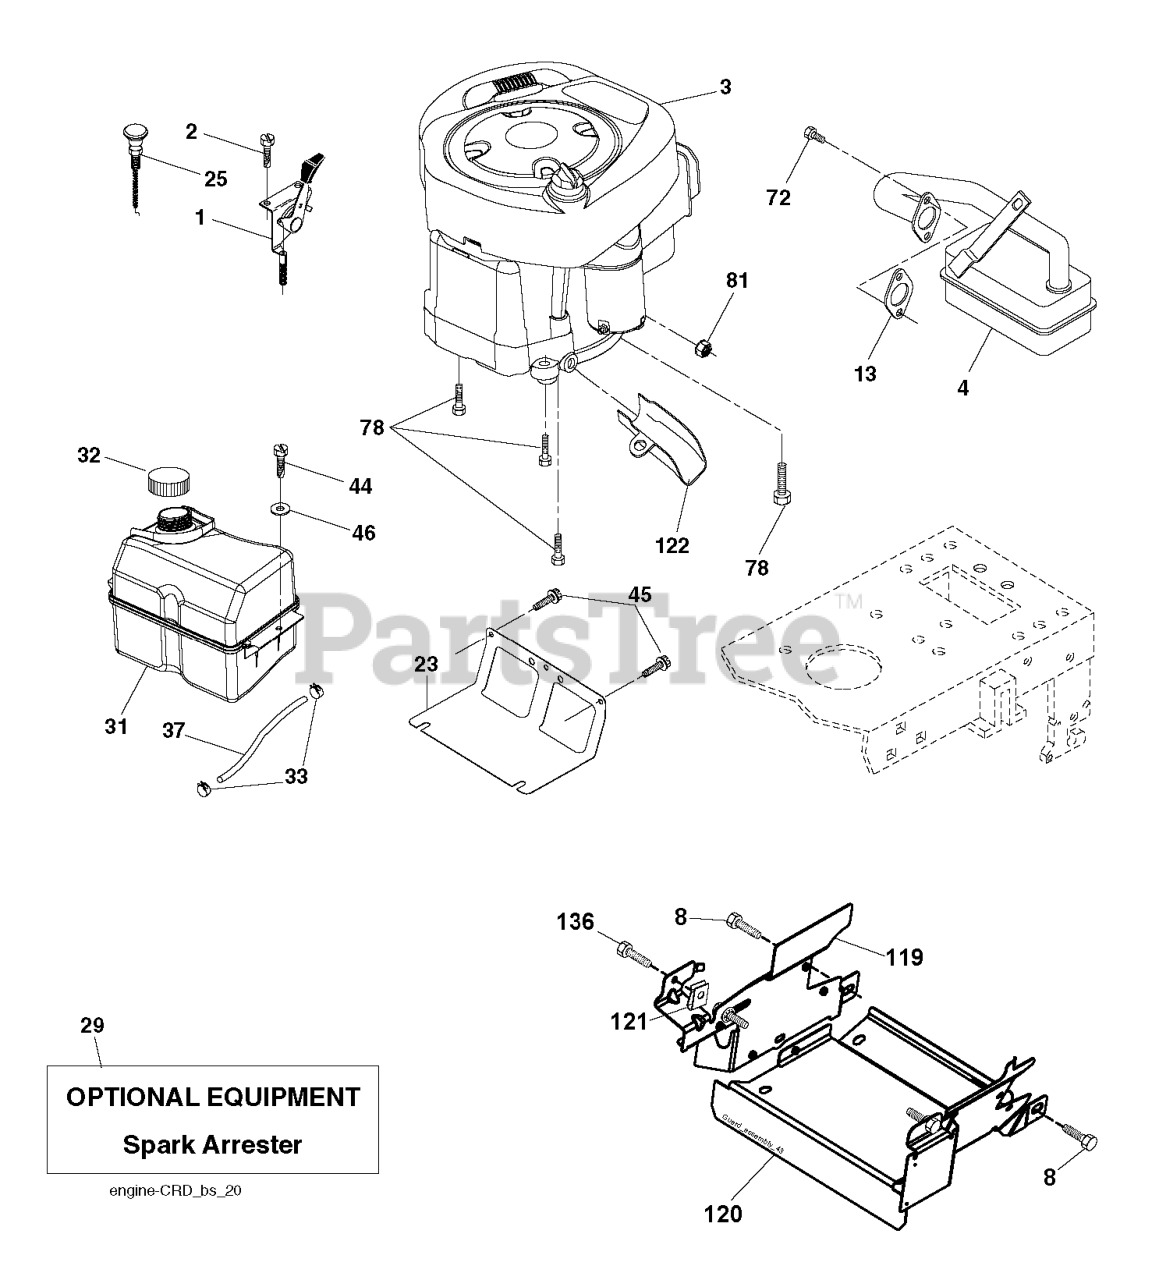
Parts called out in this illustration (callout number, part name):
1	CONTROL.THROTTLE/CHOKE.BLACK
2	SCREW
4	MUFFLER.B&S.MODEL.21.11HP.OHV
8	BOLT.5/16-18UNCX3/4 W/SEMS.BLK
13	REPL BY 532 27 22-93
23	SHIELD.BROWNING.DBR.GUARD
25	KNOB.ERGO.EXTENDED.RED (1 2)
29	KIT.SPARK ARRESTOR 794945 B&S
31	TANK.ASM.FRNT.DAPCO.E10
32	CAP ASM.FUEL.2.25"FR.
33	HOSE CLAMP
37	LINE.FUEL.20
44	SCREW HEXWSHR 1/4-20X3/4
45	SCREW, 3/8-16X3/4
72	SCREW.SOCKET HD.5/16-1
78	SCREW.3/8-16
81	NUT
119	LENKRAD
120	GUARD 532199767
122	EXTENSION DRAIN OIL
136	SCREW.1/4-20X5/8
